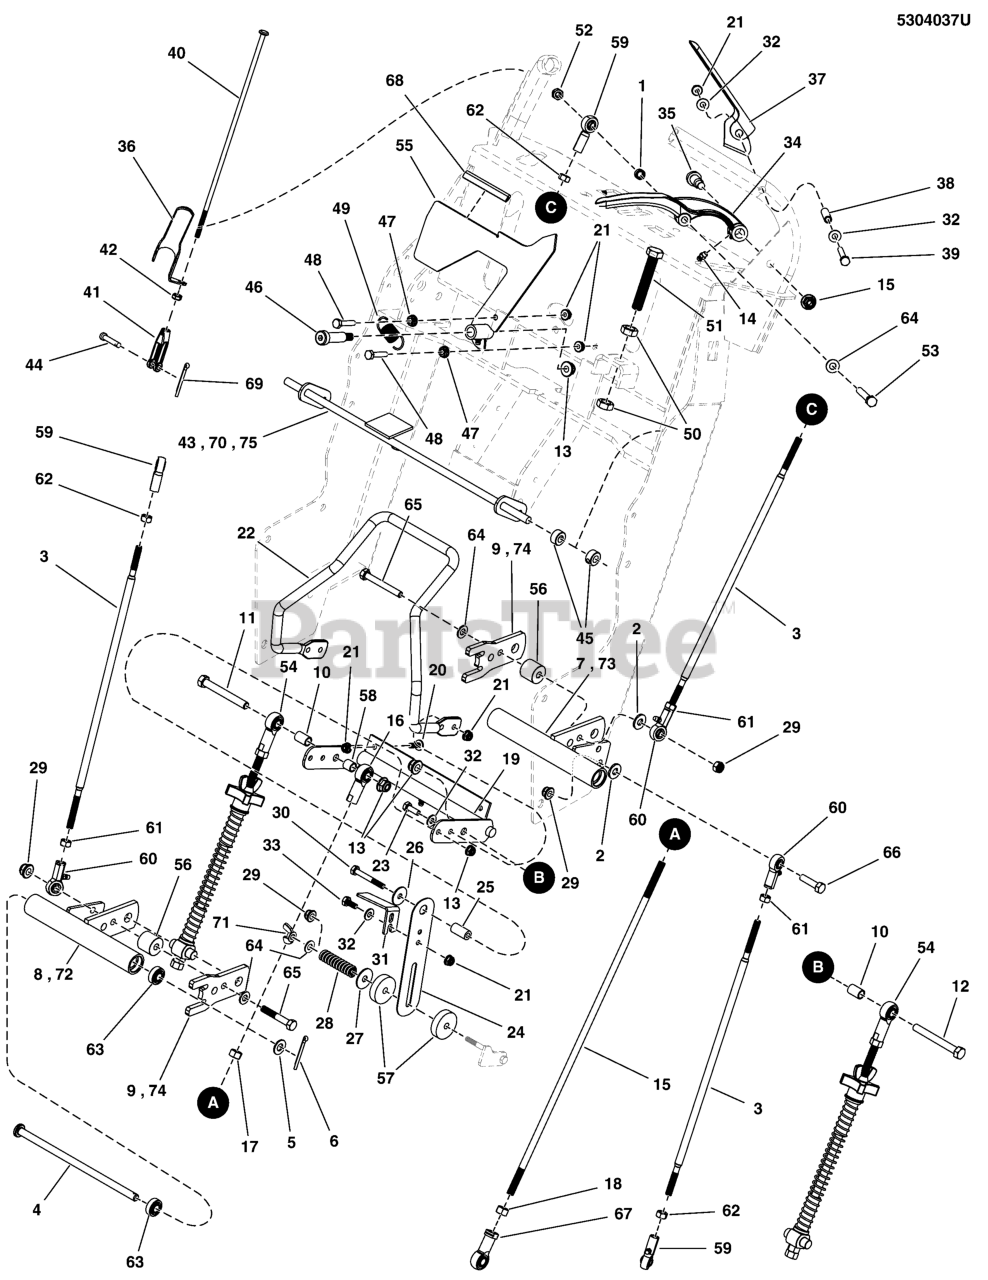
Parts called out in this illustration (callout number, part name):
1	SPACER, .33 X .50 X .25, PM, CZ
2	WASHER, 5/16 F436 FLAT
3	ROD, 5/16-24 X 15.48, LH-RH, CZ
4	ROD, 3/8 X 8.49, HEADED
5	WASHER, 3/8 SAE
6	PIN, COTTER, 1/8 X 1-1/4
7	WELD, CENTER PIVOT HUB, LH - WALK - BLK
8	WELD, CENTER PIVOT HUB, RH - WALK - BLK
9	TAB, CONTROL PIVOT - BLK
10	SPACER, .38 X .50 X .75
11	BOLT, 3/8-16 X 3" GD5 CZ
12	BOLT, 3/8-16 X 2, GD5, CZ
13	NUT, 3/8-16 HEX NYLOCK FLANGE
14	GREASE FITTING, 1/4-28 STRAIGHT
15	ROD, 3/8-24, 19.00, LH-RH CZ
16	BALL JOINT, 3/8-24 FEMALE
17	NUT, 3/8-24 HEX
18	NUT, 3/8-24 HEX, LH
20	SCREW-TRUSS HD TORX DR 1/4-20X0.750 T27
21	NUT, 1/4-20 HEX NYLOCK FLANGE
22	WELD, SPEED BAR - BLK
23	BOLT, 1/4-20 X 3/4 GD5 CZ
24	PLATE, FRICTION CONTROL, SS
25	SPACER, .26 X .50 X 1.00
26	WASHER, 1/4 FENDER
27	WASHER, 5/16 FENDER
28	SPRING, COMP, .40 X .60 X 2.25, BLACK
29	NUT, 5/16-18 HEX NYLOCK FLANGE
30	BOLT, 1/4-20 X 2", GD5
31	BRACKET, SWITCH ENGAGEMENT - BLK
32	WASHER, 1/4 SAE
33	HHCS, 1/4-20 X 0.625, GR5, ZINC/CLEAR
34	HANDLE, REVERSING - BLK
35	BOLT, 3/8-16 X 1/2, 1.00 SHOULDER, CZ
38	SPACER, .26 X .38 X 1.25, CZ
39	BOLT, 1/4-20 X 1-3/4 GD5 CZ
40	ROD, OPC LINK, SNP PRO WB
42	HN, 1/4F GR5 YZ
43	WELD, OPC ROD, WALK - BLK
44	PIN, CLEVIS, 1/4 X 7/8, PLATED
45	COLLAR, 3/8 SET
46	BOLT-3/8-16 x 1-1/2, 1/2 SHOULDER
47	NUT, 1/4-20 HEX SERR. FLANGE
48	BOLT, 1/4-20 X 1-1/4 GD5 CZ
49	SPRING, EXT, 0.525 X 0.058 X 2.250 SS
50	NUT, 1/2-20 HEX JAM
51	BOLT, 1/2-20 X 2-1/2, FLT
52	NUT, 5/16-18 HEX NYLON LOCK
53	BOLT, 5/16-18 X 2-1/4 GD5 CZ
54	SEE MOTION CONTROL GROUP - SPRING ASSEMBLIES
55	WELD, SPEED INDICATOR, W25 - BLK
56	SPACER, .33 X 1.00 X .88, CZ
57	PAD, T-712 FRICTION MATERIAL
58	SPACER, .38 X .50 X .50
59	BALL JOINT 5/16-24 RH FEMALE BRONZE RACE
60	BALL JOINT 5/16-24 LH FEMALE BRONZE RACE
61	NUT, 5/16-24 HEX, LH
62	NUT, 5/16-24 HEX
63	BEARING, .375" ID X .875" OD X .341" THK
64	WASHER, 5/16" SAE
65	BOLT, 5/16-18 X 2-1/2 GD5 CZ
66	BOLT, 5/16-18 X 1-1/4 GD5 CZ
67	BALL JOINT, 3/8-24 FEMALE, LH
68	U-CHANNEL, RPVC #6236 X 4"
69	PIN, 3/32 X 0.750, COT, ZINC/CLEAR
70	WELD, OPC ROD, WALK - BLK
71	NUT, Wing, 5/16-18
72	WELD, W25 CONTROL PIVOT, RH - BLK
73	WELD, W25 CONTROL PIVOT, LH - BLK
74	TAB, PIVOT, W35 - BLK
75	WELD, OPC ROD, WALKBEHIND - BLK
